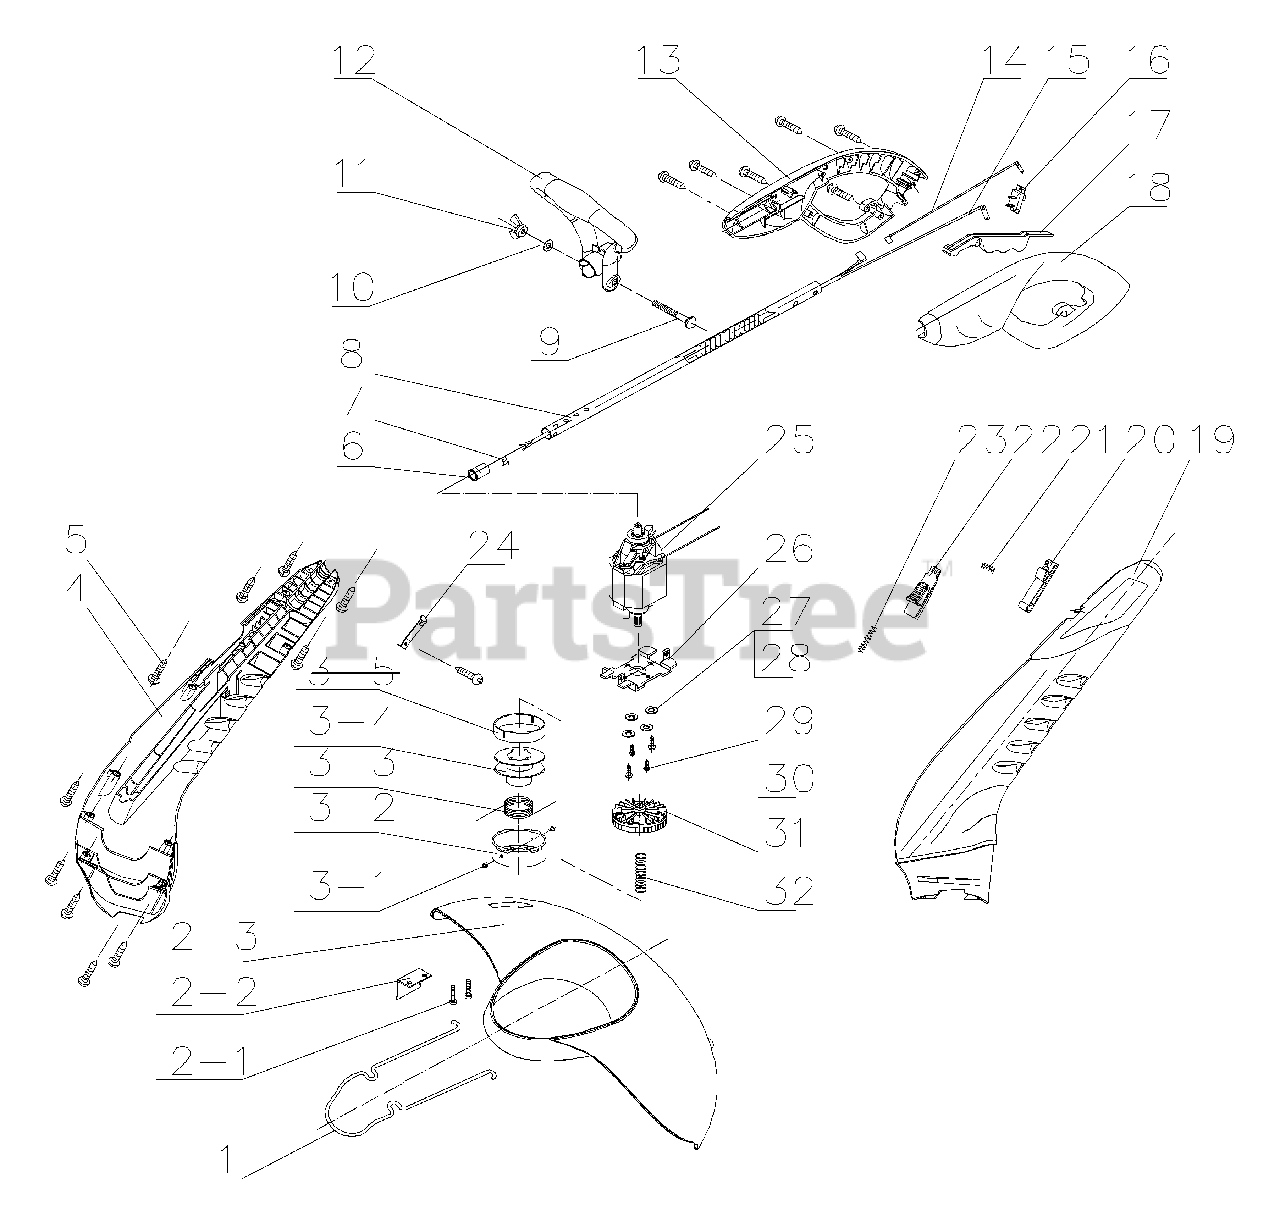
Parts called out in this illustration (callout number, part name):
1	PROJECTIVE GUARD
2	GUARD ASS'Y
3	SPOOL CARRIER ASS'Y
4	HOUSING (R)
7	SNAP BUTTON
12	CENTRAL HANDGRIP
13	UPPER HANDGRIP (R)
18	UPPER HANDGRIP (L)
19	HOUSING (L)
25	MOTOR 120V
26	MOTOR PLATE
31	CUTTER ASS'Y
